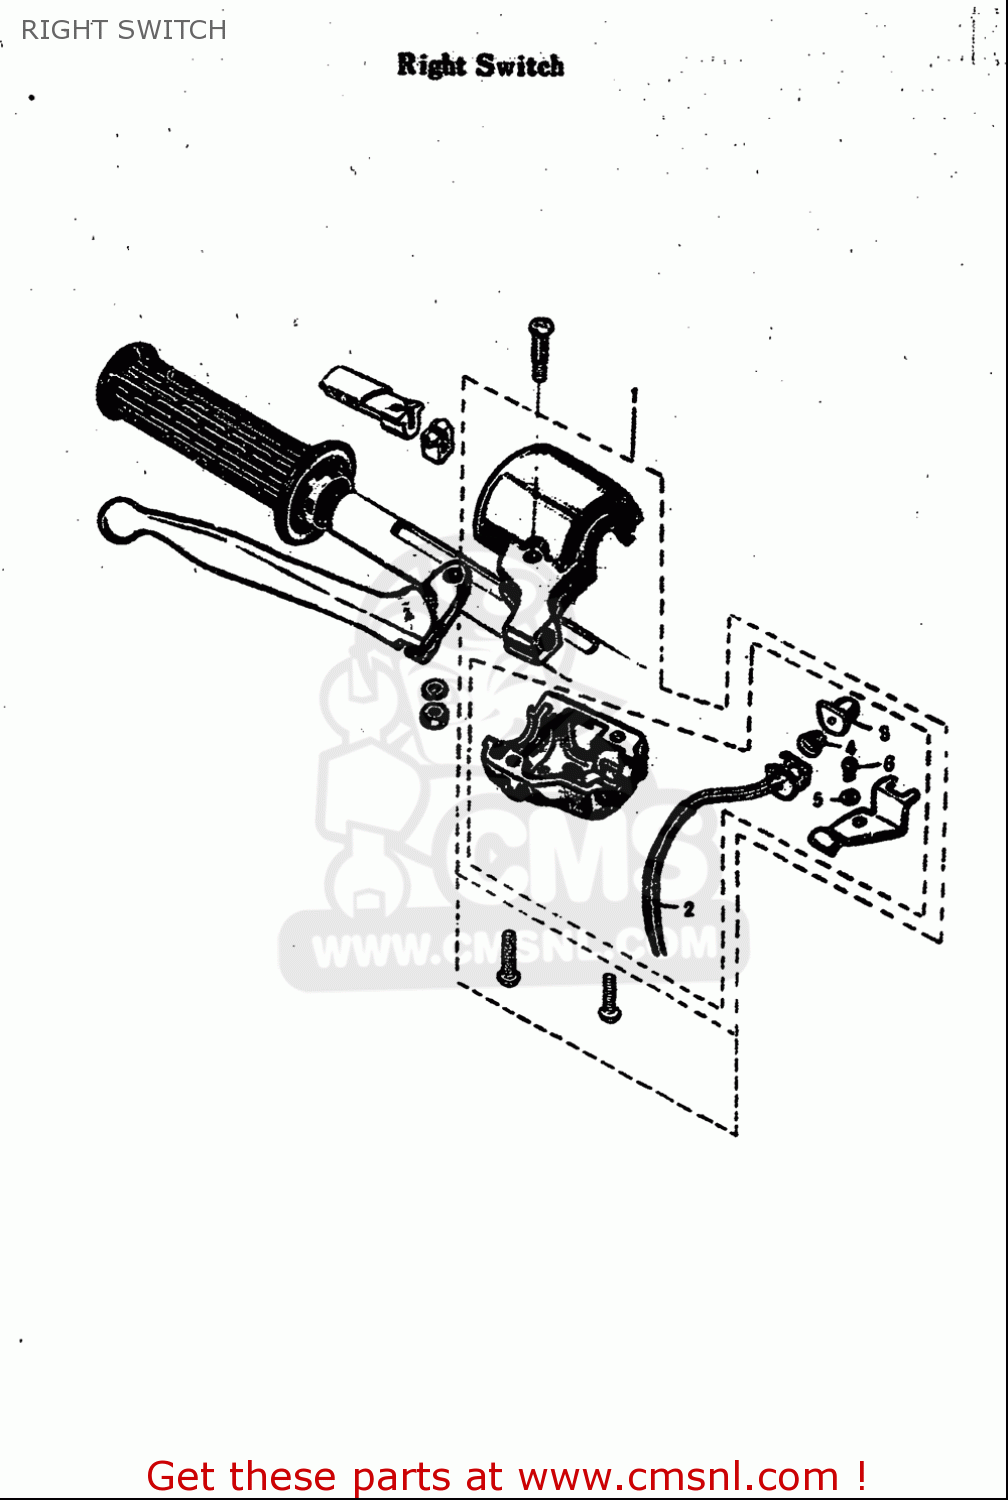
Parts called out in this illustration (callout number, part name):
3	BUTTON
4	SPRING
5	WASHER,LOCK
